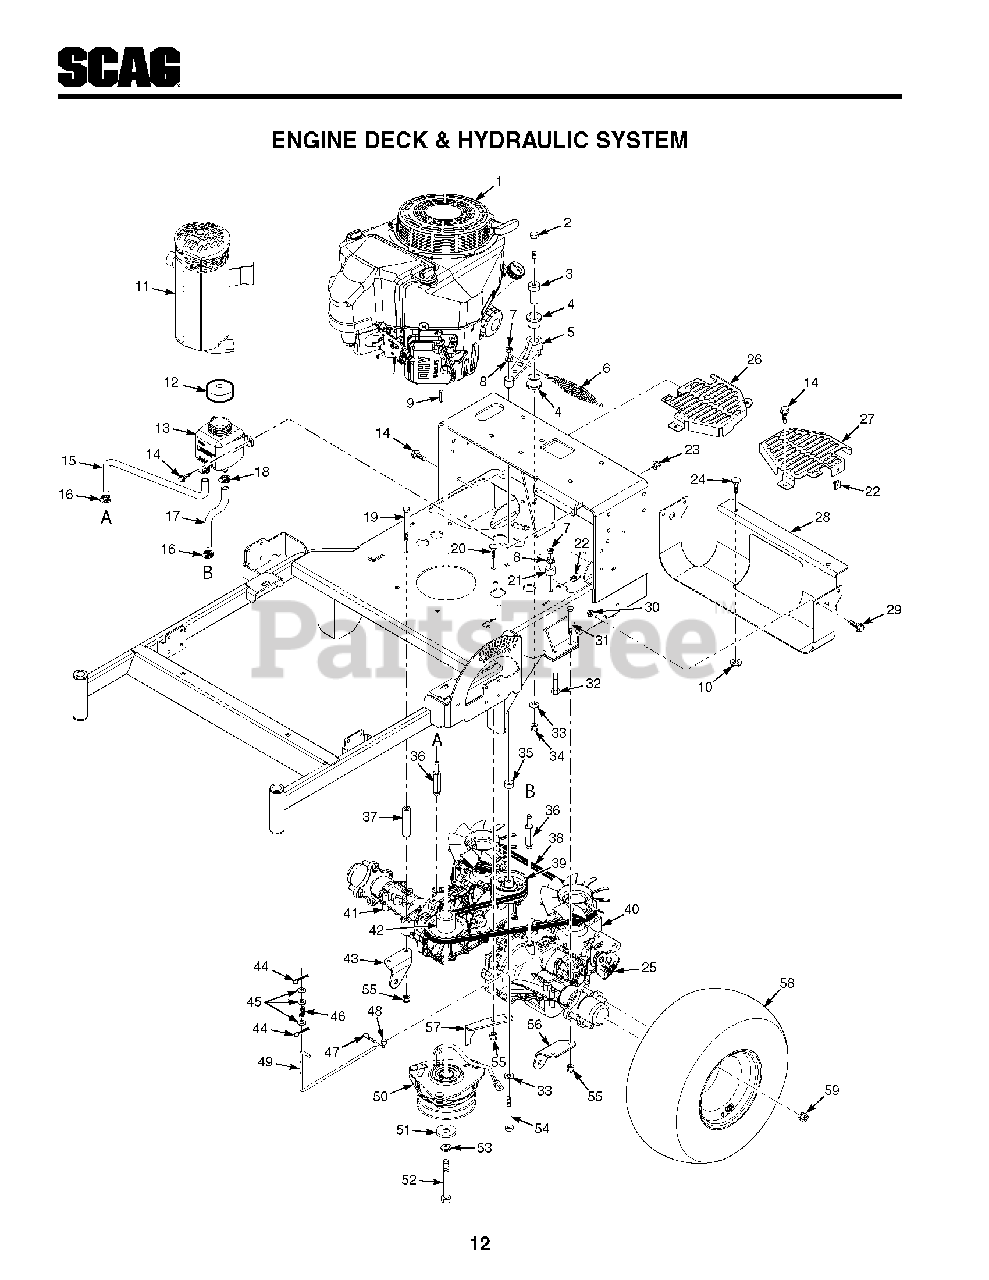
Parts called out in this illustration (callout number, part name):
1	Engine, Kawasaki FS481V
1	Engine, Kawasaki FS541V
1	Engine, Kawasaki FS600V (Recoil Start)
1	Engine, Kawasaki FS600V (Electric Start)
1	Engine, Kawasaki FS651V (Electric Start)
2	Bolt, Hex Head 3/8-16 x 3"
3	Pivot, Idler
4	Bearing
5	Idler Arm
6	Spring, Transmission Idler
7	Nut, Center Lock 3/8-16
8	Nut, Serrated Flange 3/8-16
9	Key, 1/4 x 1/4 x 2-1/2"
10	Nut, Push-On 5/16-18
11	Muffler, Kawasaki (FS481, FS541, FS600)
11	Muffler, Kawasaki (FS651) - SWZT61
11	Manifold, Kawasaki (FS651) - SWZT61
13	Reservoir Assembly
14	Bolt, Hex Head, Serrated Flng 1/4-20 x 3/4"
15	Hose, RH Transmission
16	Clamp, 0.69" Max Dia.
17	Hose, LH Transmission
18	Clamp, 0.87" Max Dia.
19	Bolt, Hex Head 5/16-18 x 6-1/2"
20	Bolt, Carriage 5/16-18 x 1"
21	Spacer
22	U-Nut, 1/4-20
23	Nut, Elastic Stop 1/4-20
24	Bolt, Carriage 5/16-18 x 3/4
25	Spring, RTN
26	Fan Cover, RH
27	Fan Cover, LH
28	Skid Plate
29	Cpscrw, 5/16-18 x 3/4"Serrated Flange HH
30	Nut, Serrated Flange 5/16-18
31	Bolt, Hex Head 5/16-18 x 3"
32	Bolt, Hex Head 3/8-16 x 1-3/4"
33	Flatwasher, 3/8-.391 x .938 x .105 Hardened
34	Nut, Elastic Stop 3/8-16
35	Spacer
36	Fitting, Transmission
37	Spacer, Axle
38	Belt, Transmission Drive
39	Pulley, 3-1/2" Dia.
40	Transaxle Assy., (ZH-GMCC-3LUB-1MXX)
41	Transaxle Assy., (ZH-KMCC-3LUC-1MXX)
42	Pulley, 4-1/2" Dia. 1" Bore
43	Pusharm Mount Bracket, RH
44	Cotter Pin, 3/32 x 1"
45	Flatwasher, 1/4-.312 x .750 x .065
46	Spring, Dump Valve Link
47	Pin, Rue Cotter 3/8" Dia.
48	Joint, Swivel
49	Link, Dump Valve
50	Electric Clutch Assembly
51	Flatwasher, 7/16-.469 x 1.75 x .25
52	Bolt, Hex Head 7/16-20 x 3" w/t Patch
53	Lockwasher, 7/16" spring
54	Bolt, Hex Head 3/8-16 x 3-3/4"
55	Nut, Elastic Stop 5/16-18
56	Pusharm Mount Bracket, LH
57	Bracket, Anti-Rotation
58	Wheel Assembly 18 x 6.5-8 (36" Only)
58	Tire 18 x 6.5-8 (36" Only)
58	Wheel Assembly 18 x 8.5-8
58	Tire 18 x 8.5-8
59	Wheel Nut, 1/2-20
